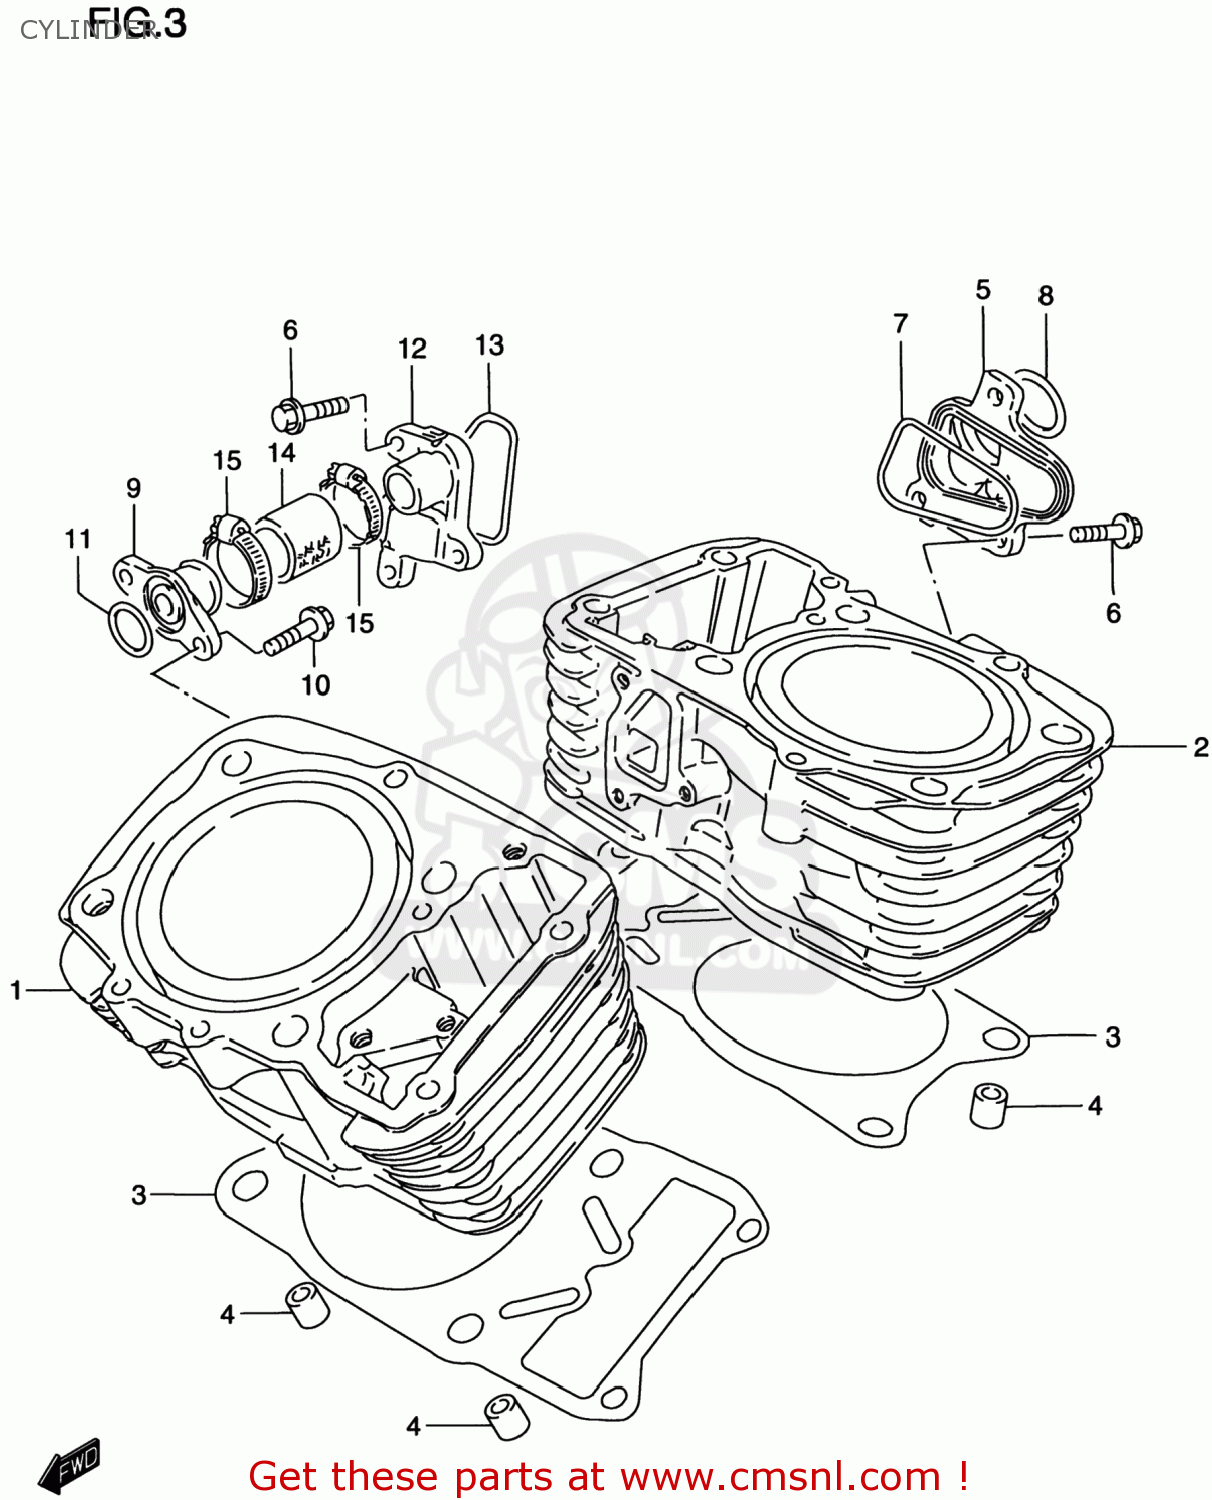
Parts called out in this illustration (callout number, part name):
1	CYLINDER,FR
2	CYLINDER
3	GASKET,CYLINDER (NAS)
4	PIN
5	CHAMBER,WATER,INLET
6	BOLT
7	O RING,INLET WATER CHAMBER
8	O RING(D:2.3,ID:24.4)
9	UNION,WATER INLET
10	BOLT
11	O RING(D:2.4,ID:15.8)
12	CHAMBER,WATER OUTLET
13	O RING,OUTLET WATER CHAMBER
14	HOSE,RADIATOR INLET
15	CLAMP
